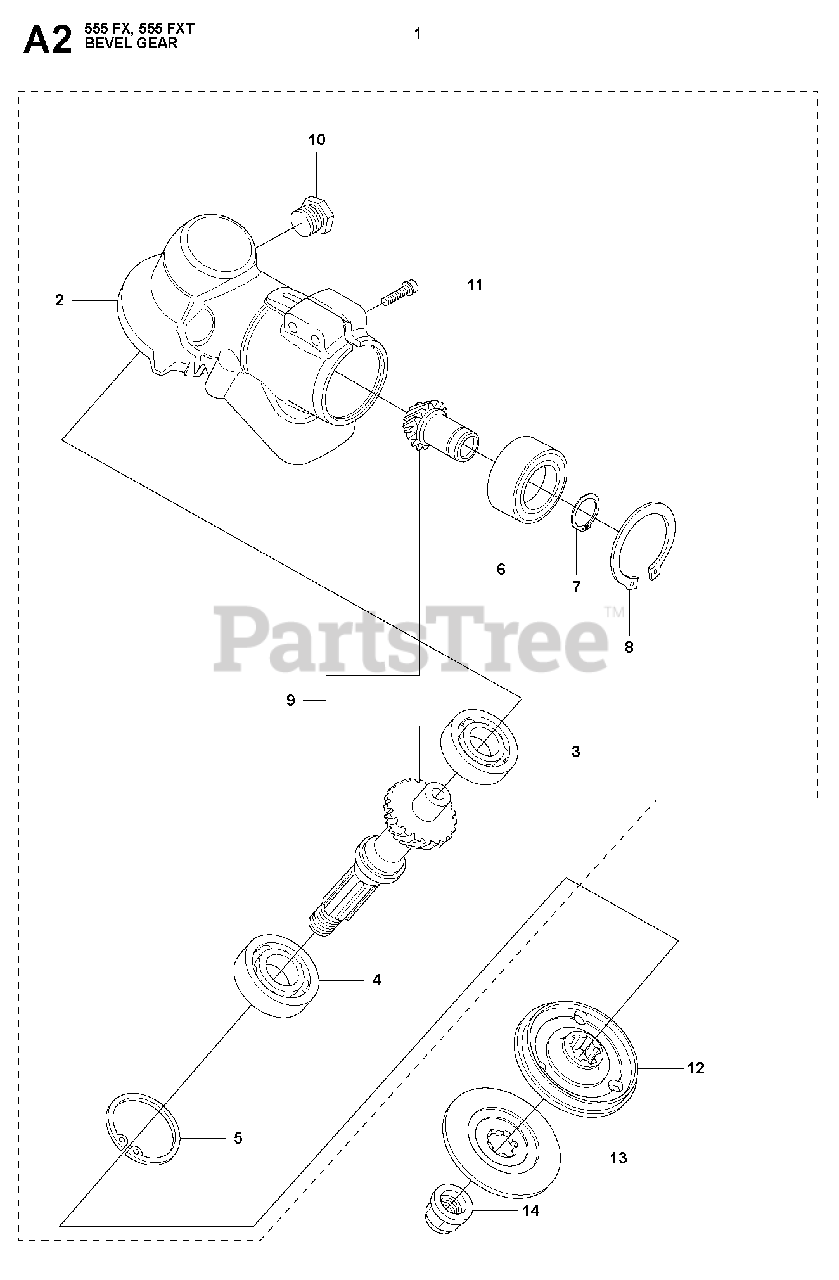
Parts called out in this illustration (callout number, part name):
1	BEVEL GEAR
2	%GEAR HOUSING
3	BALL BEARING
4	BALL BEARING
5	RETAINING RING SGH 35
6	BEARING
7	RETAINING RING SGA 15
8	RETAINING RING
9	BEVEL GEAR
10	PLUG
11	SCREW
13	SUPPORT FLANGE
14	BLADE NUT
